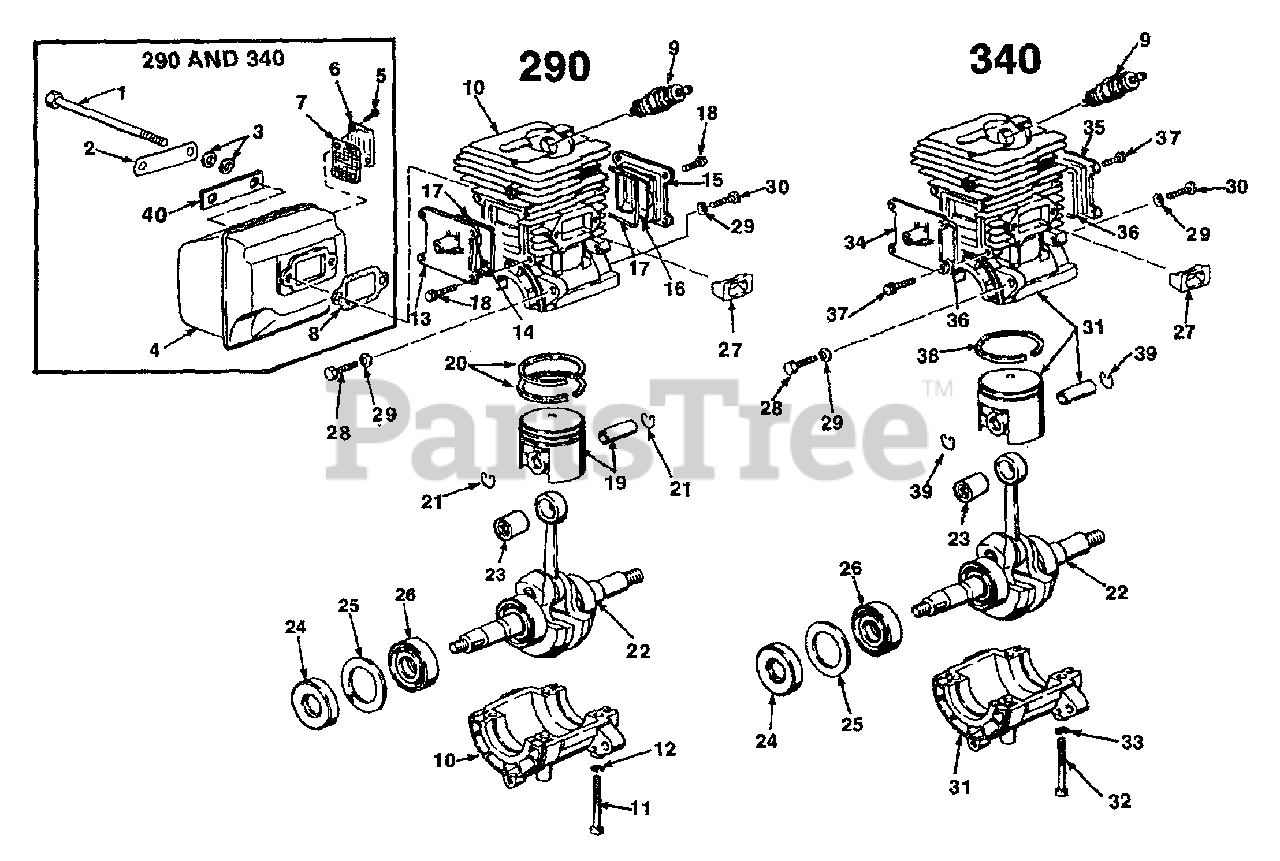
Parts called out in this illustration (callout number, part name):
1	SCREW-(M6 x 90)
2	PLATE-Locking
3	WASHER-Belleville
4	MUFFLER ASSEMBLY
6	COVER-Muffler
7	SPARK ARRESTOR
8	MUFFLER GASKET
9	SPARK PLUG (Champion CJ6Y)
10	CRANKCASE & CYLINDER
11	SCREW-M5 x 45
12	WASHER-Lock
13	COVER-Transfer port
14	INSERT-Transfer port
15	COVER-Transfer port
16	INSERT-Transfer port
17	"O" RING
18	SCREW-M4 x 12
19	PISTON & PIN ASSEMBLY
20	PISTON RING
21	RING-Piston pin retaining
22	CRANKSHAFT ASSEMBLY
23	BEARING-Needle roller
24	SEAL-Main
25	RETAINER-Bearing
26	BEARING-Ball
27	INSERT-INTAKE PORT
28	SCREW-(M5 x 23)
29	WASHER-Flat (M5)
30	SCREW-(M5 x 18)
31	CRANKCASE & CYLINDER W/Piston Assembly (Matched)
33	WASHER-Lock
34	TRANSFER PORT COVER ASSEMBLY
35	TRANSFER PORT COVER ASSEMBLY
36	"O" RING
37	SCREW (M4 x 12)
38	PISTON RING
39	RING-Piston pin retaining
40	PLATE-Support
